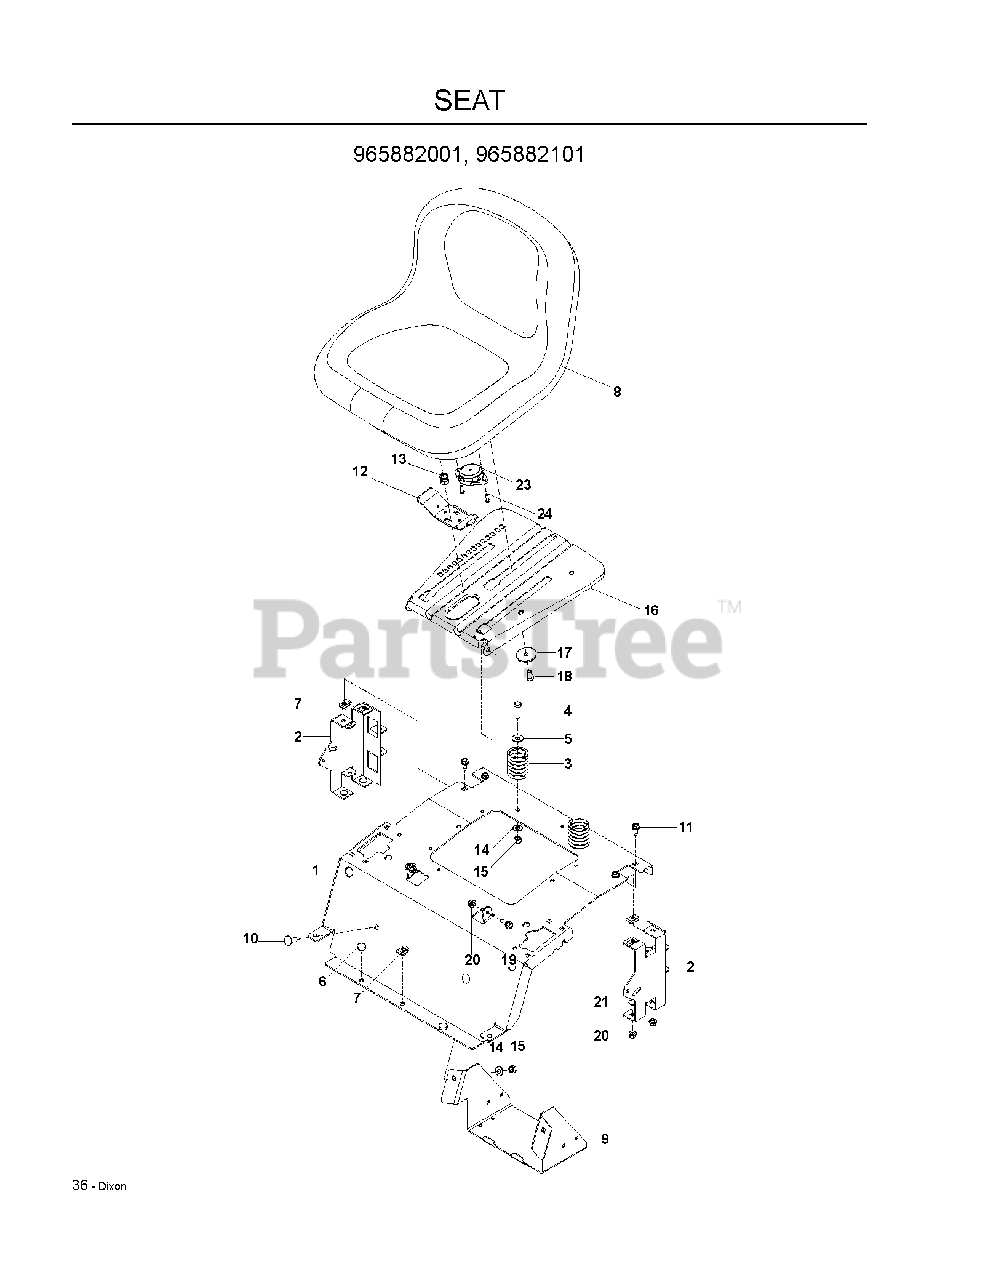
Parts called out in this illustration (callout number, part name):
1	SUPPORT.SEAT.FLAT.ORAN*SUBS/2*
2	SUPPORT, REAR SEAT, BLACK
3	SPRING, SEAT
4	HCS 3/8C X 1 1/4 GR5
5	WASHER 3/8 FLAT
6	GROMMET, BUMPER
7	U-CLIP 5/16-18 NUT RETAINER
8	SEAT,BLACK W/ARMREST PROVISION
9	BOX, BATTERY, BLACK
10	RHSNB 3/8C X 1
11	BOLT 5/16-18 X 3/4
12	HANDLE.SLIDE.SEAT.TEX.BLACK
13	SPRING.LATCH.SEAT.TEX
14	WASHER 3/8 SAE FLAT
15	NUT 3/8-16 NYLOC
16	PAN.ASM.SEAT.3PT
17	WASHER, 3/8 SPEC
18	HCS 3/8-16 X 5/8 GR 5 ZD
19	BOLT, SHOULDER
20	5/16-18 NYLOC FLANGE NUT
21	BOLT 5/16C X 3/4" CARRIAGE
22	5/16-18X2-1/4 CAR BL
23	SEAT SWITCH MILSCO
24	SCR 1/4-20X3/4 SLTD RDHD GR2ZD
